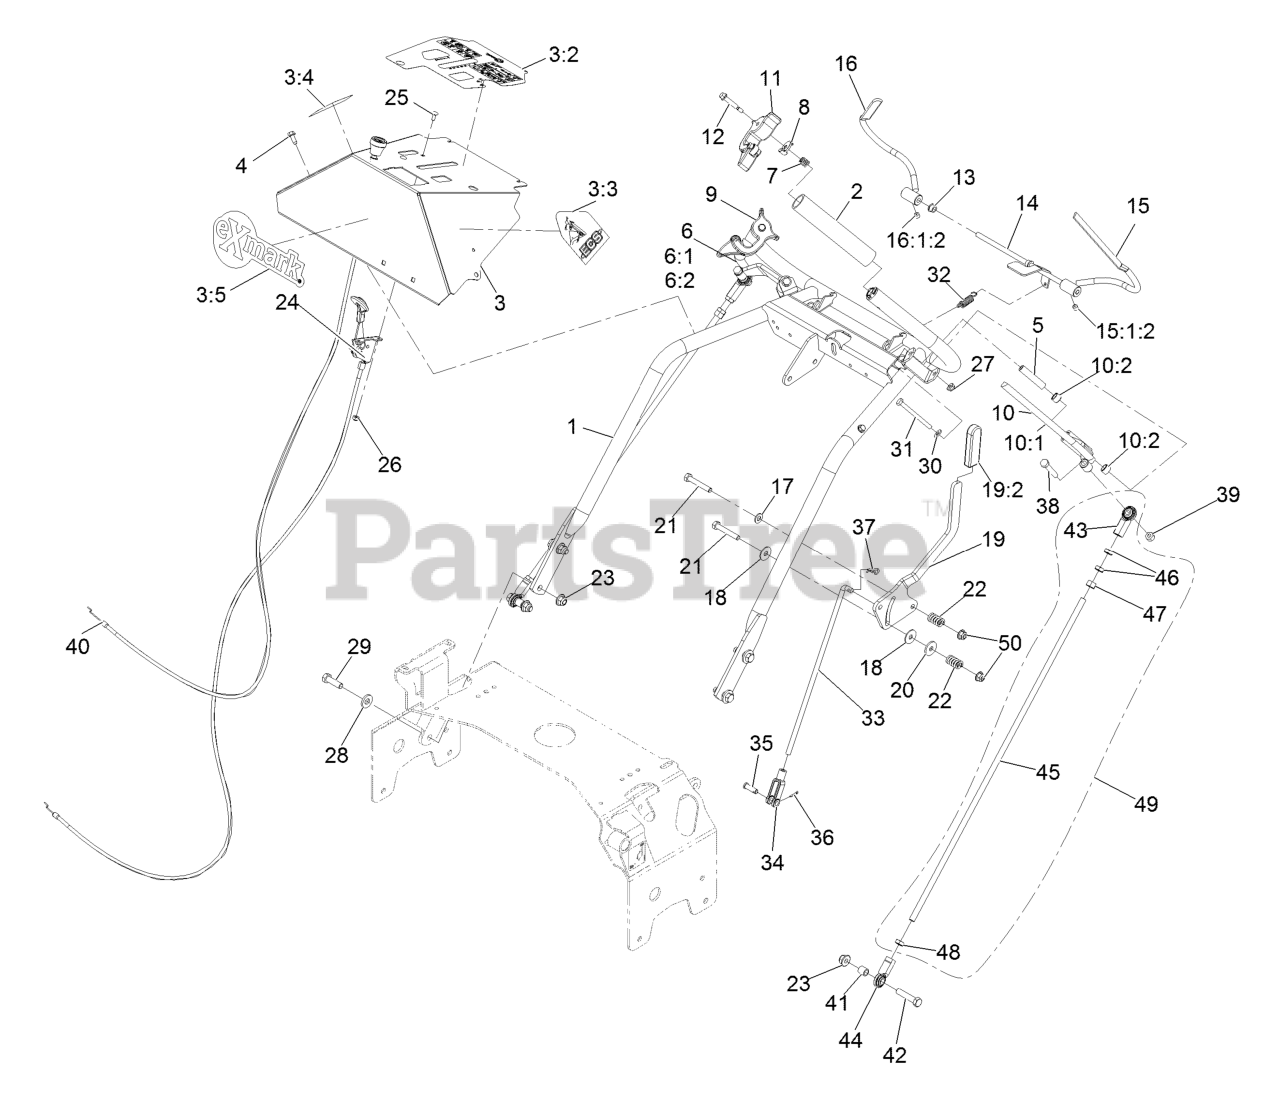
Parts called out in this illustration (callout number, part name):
1	WELD, HANDLE
2	GRIP-BAR, HANDLE
3	ASM, CONSOLE W/ DECALS
3:2	DECAL-CONSOLE TTX KAW
3:3	DECAL,LH ECS INSTRUCTION
3:4	DECAL,RH ECS INSTRUCTION
3:5	DECAL,EXMARK LOGO
4	SCREW-HWH
5	BUSHING-LEVER, DRIVE
6	DRIVE LEVER-ASM, RH
6:1	WLD,RH DRIVE LEVER
6:2	BUSHING-SLEEVE
7	SPRING-TANK, FUEL
8	LATCH, ECS
9	ASM,LATCH RH THUMB
10	DRIVE LEVER-ASM, LH
10:1	WLD,LH DRIVE LEVER
10:2	BUSHING-SLEEVE
11	ASM,LATCH LH THUMB
12	SCREW-SHOULDER
13	BUSHING-NYLON
14	WLD,OPC LEVER AXLE
15	WLD,LH OPC LEVER
15:1:2	SCREW-SET
16	WLD,RH OPC LEVER
16:1:2	SCREW-SET
17	WASHER-PLAIN
18	WASHER-FRICTION
19	LEVER, SHIFT W/GRIP
19:2	GRIP-HANDLE, STEERING
20	WASHER-FRICTION
21	SCREW-HH
22	SPRING-COMPRESSION
23	NUT-HF, NI
24	CONTROL-THROTTLE
25	BOLT-CARR
26	NUT-LOCK, NI
28	WASHER-BELLEVILLE
29	SCREW-HH
30	WASHER-FLAT
31	SCREW-HH
32	SPRING-EXTENSION
33	ROD,SPEED CONTROL
34	YOKE-ADJUSTABLE
35	PIN-CLEVIS
36	PIN-COTTER
37	PIN-COTTER
38	SCREW-HH
39	NUT-LOCK, NI
40	CABLE, CHOKE
41	SPACER-TUBE, PUMP LINK
42	SCREW-HH
43	JOINT-BALL, END
44	JOINT-BALL END, LH
45	LINK,DRIVE (PLTD)
46	NUT-HJ
47	NUT-HEX
48	NUT-HEX JAM, LH
49	DRIVE LINK ASM
50	NUT-HF, NI
